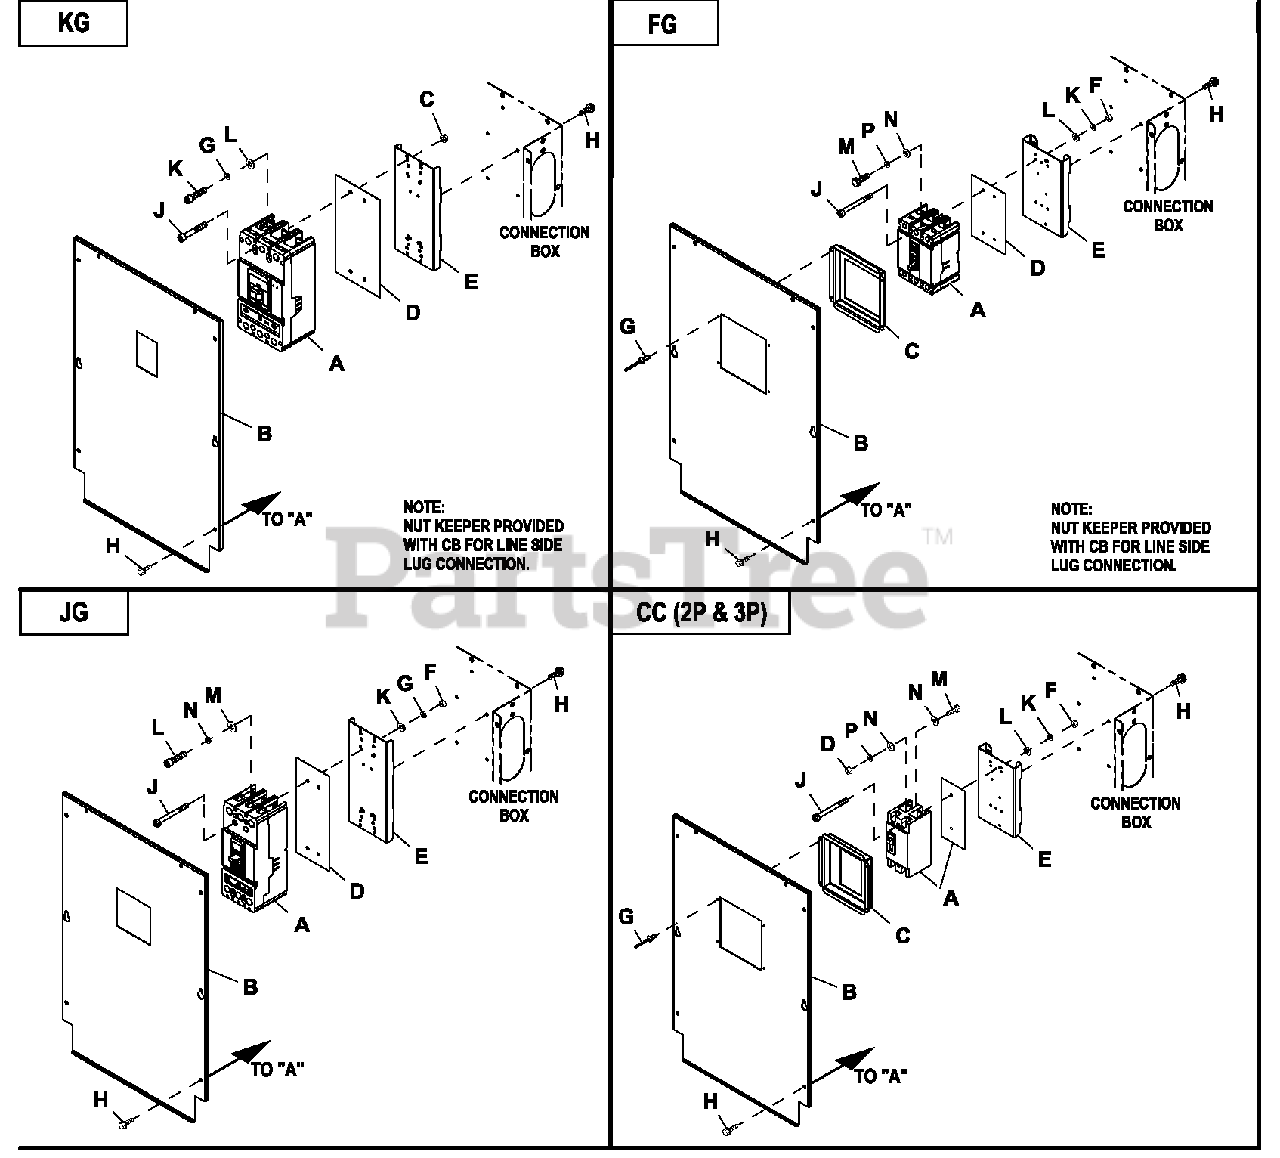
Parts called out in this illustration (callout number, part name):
A	CB 0300 3P 600V E KG LL
B	COVER CB E KG C2 CONBOX
C	NUT FLANGE M6-1.0 NYLOK
D	INSULATOR CB E 3P KG
E	STANDOFF CB MOUNT CONBOX
G	WASHER LOCK M8-5/16
H	SCREW HWHT M 6-1 X 16 N WA Z/JS
J	SCREW SHC M6-1.0 X 50 C8.8
K	SCREW SHC M8-1.25 X 20 G8
L	WASHER FLAT 5/16-M8 ZINC
A	CB 0060 3P 480V E FG LL
B	COVER CB C2 CPL
C	COVER CB DISH 3P E FG
D	INSULATOR CB 3P E TYPE CC/FG
E	STANDOFF CB BOX CONBOX
F	NUT HEX #8-32 STEEL
G	RIVET POP .125 X .275 SS
J	SCREW PPHM #8-32X1-3/4 ZINC
K	WASHER LOCK #8- M 4
L	WASHER FLAT #8 ZINC
M	SCREW HHC M 5-0.8 X 20 G8.8
N	WASHER FLAT #10 ZINC
P	WASHER LOCK M5
A	CB 0250 3P 600V E JG LL
B	COVER CB E JG C2 CONBOX
D	INSULATOR CB E 3P JG
F	NUT HEX 1/4-20 STEEL
G	WASHER LOCK M6-1/4
J	SCREW RHM 1/4-20X3
K	WASHER FLAT 1/4-M6 ZINC
L	SCREW SHC M8-1.25 X 20 G8
M	WASHER FLAT 5/16-M8 ZINC
N	WASHER LOCK M8-5/16
A	CB 0175A 2P 240V E CC LL
C	COVER CB DISH 2P E CC
D	NUT HEX M 5-0.8 G8 CLEAR ZINC
J	SCREW RHM #8-32 X 3-1/4
